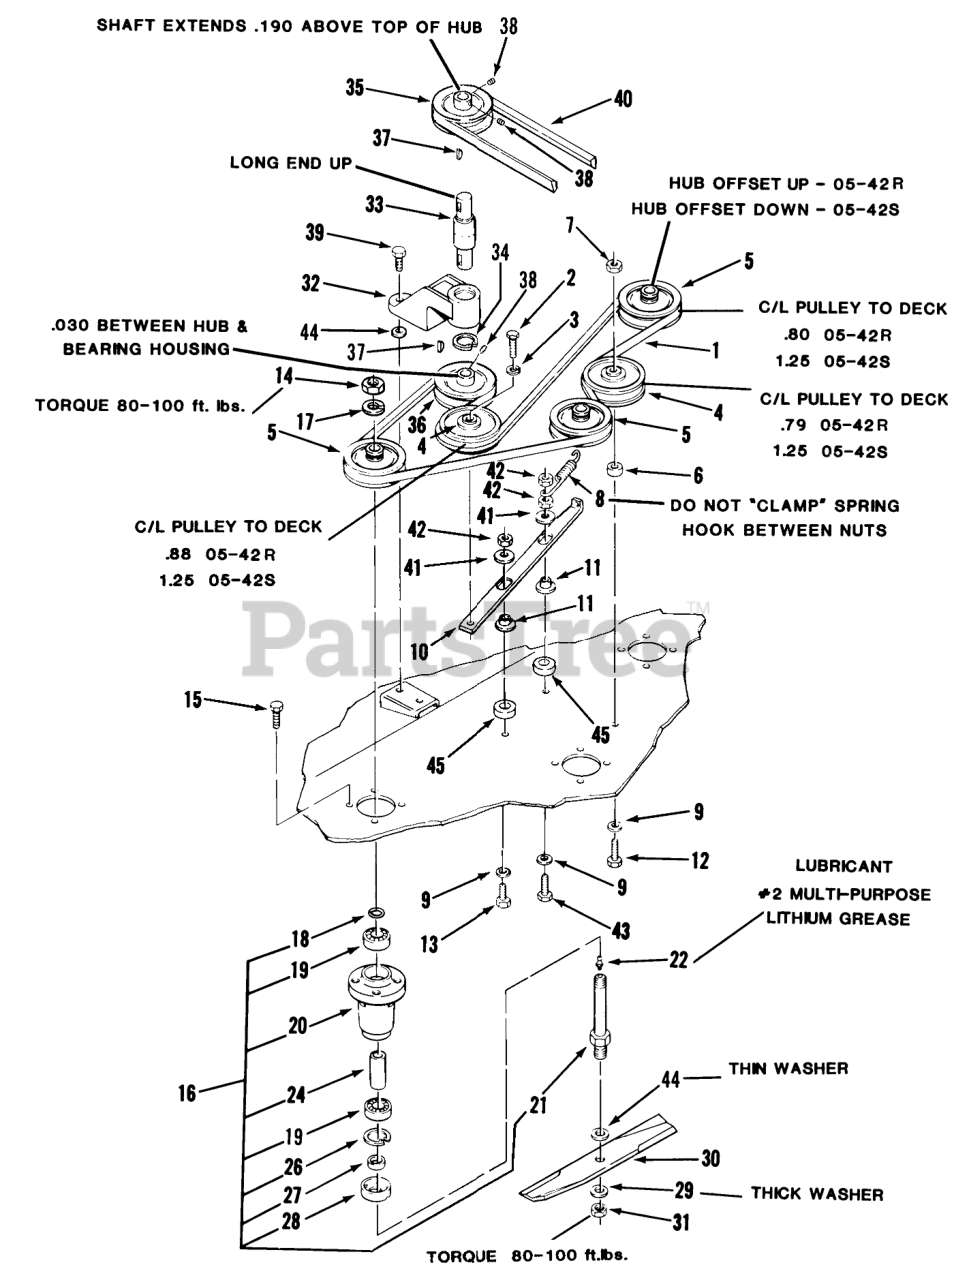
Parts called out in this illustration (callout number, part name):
1	V-BELT
2	Bolt
3	LOCKWASHER
4	PULLEY-IDLER
5	PULLEY
6	SPACER
7	NUT
8	SPRING-EXTENSION
9	WASHER
10	BAR-SLIDER
11	SPACER-BUSHING
12	Bolt
13	Bolt
13	BOLT
14	Jam Nut
15	Bolt
16	Spindle Assembly
17	Lockwasher
18	O RING
19	BEARING-BALL
20	HOUSING-SPINDLE
21	SHAFT-SPINDLE
22	Zerk
26	Ring-Snap
27	SPACER-BLADE
28	CUP-SPINDLE
29	Washer
30	BLADE KIT
30	14IN BLADE KIT
31	Nut-Jam
32	Jack Shaft Housing
33	BEARING-INT SHAFT
34	Snap Ring
35	PULLEY-LOWER
36	PULLEY-SPLIT
37	KEY-WOODRUFF
38	Set Screw
39	Bolt
40	V-BELT, PTO DRIVE
40	BELT-V
41	WASHER
42	NUT
43	Bolt
44	Washer
45	SPACER
